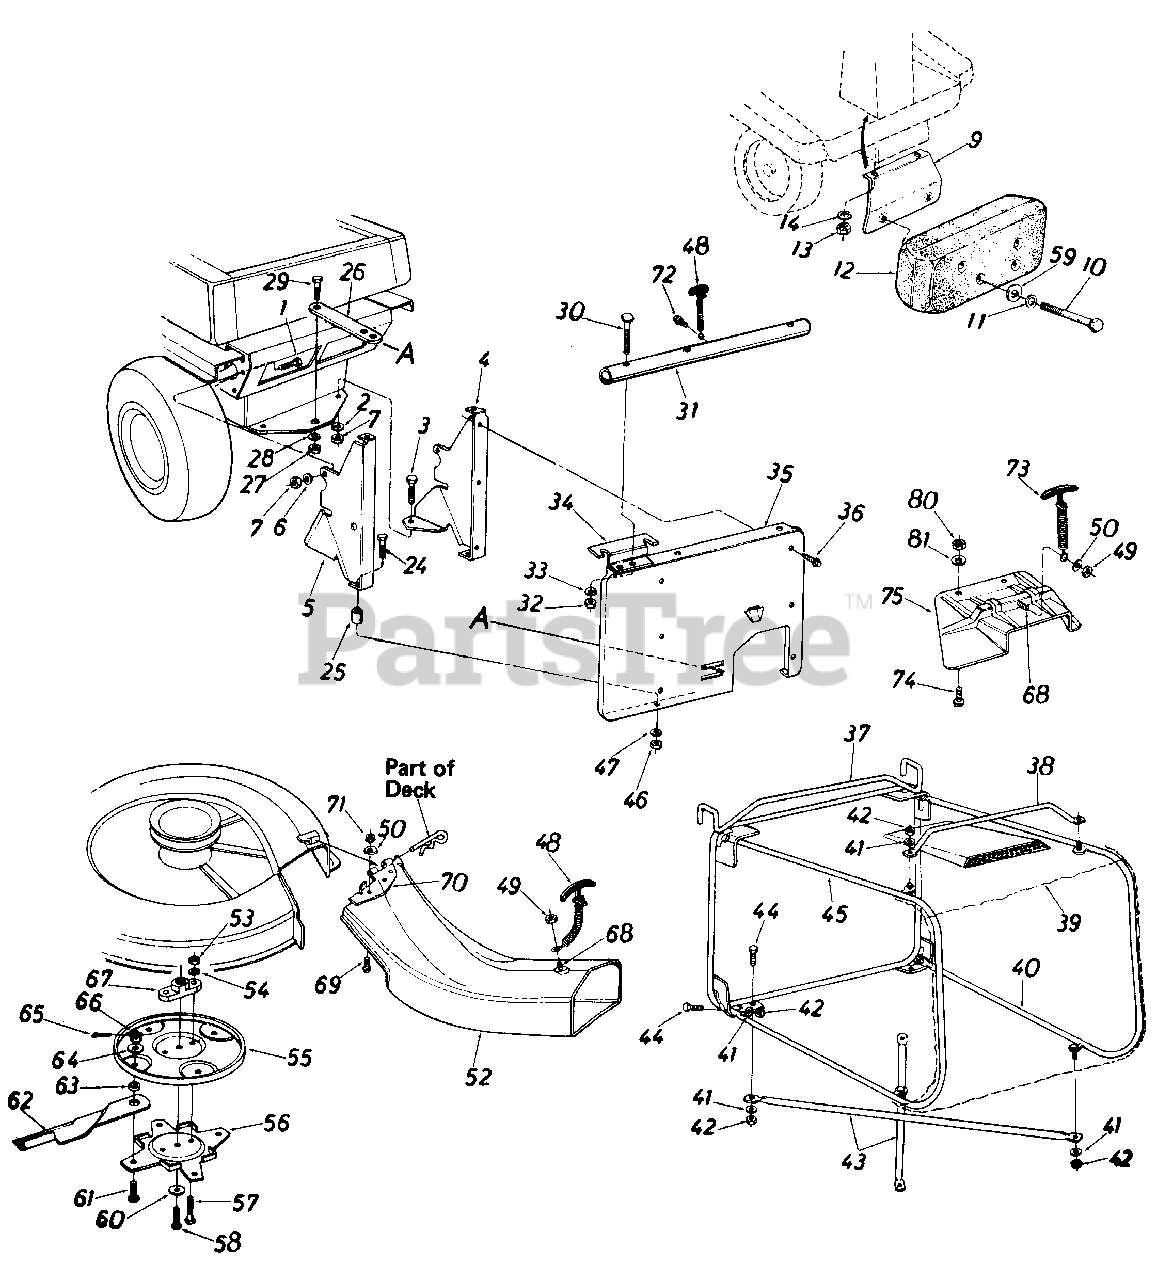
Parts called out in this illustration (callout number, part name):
1	Hex Bolt 5/16-18 x 1.0" Lg.*
2	L.-Wash. 5/16" I.D.*
3	Hex Bolt 5/16-18 x 1.0" Lg.*
4	Catcher Support Brkt - R.H.
5	Catcher Support Brkt - L.H.
6	L.-Wash. 5/16'' I.D.*
7	Hex Nut 5/16-18 Thd.
9	Counterweight Support Brkt. Ass'y .
10	Hex Bolt 3/8-16 x 4.5" Lg.*
11	Belleville Wash. .40" I.D. x .88" O.D.
12	Counterweight 38 Ibs.
13	Hex Nut 5/16-18 Thd.*
14	L.-Wash. 5/16" I.D.*
24	Hex Bolt 5/16-18 x 1.50" Lg.*
25	Spacer .380" I.D. x .47" O.D. x 1.0" Lg.
28	L.-Wash. 1/2" I.D.*
29	Hex Bolt 1/2-20 x 1.0" Lg.*
30	Curved Carriag Bolt 5/16-18 x 1.75" Lg.
33	L.-Wash. 5/16" I.D.*
34	Grass Catcher Support Plate
35	Rear Discharge Panel
36	Hex Wash. Hd. Self Tap. Scr. 1/4-20 x .50" Lg.
37	Grass Catcher Frame Ass'y.
42	Hex L.-Nut 1/2-20 Thd
43	1 Bottom Cross Brace
44	Hex Bolt 1/4-20 x .62" Lg.*
47	L-Wash. 5/16" I.D.
48	Hook Latch Ass'y.
49	Hex L.-Nut 1/4-20 Thd.
50	Fl.-Wash. 1/4" I.D.
52	R.D. Banana Chute Ass'y.
53	Hex Nut 5/16-24 Thd.*
54	L.-Wash. 5/16" I.D.*
55	Upper Blade Disc
56	Lower Blade Disc
57	Hex Bolt 5/16-24 x 1.0" Lg. (Grade 5)
58	Hex Bolt 3/8-24 x 1.0" Lg.
59	Fl.-Wash. .39" I.D. x 1.12" O.D.
60	Bell.-Wash. 39" I.D. x 1.38"
61	Shld. Bolt. .50" Dia. x .360 Spec.
62	30" Blade Tip (4-Req'd.)
63	Spacer .505" I.D. x .75" O.D. x 1.25" Lg.
64	Fl.-Wash. .50" I.D. x 1.25" O.D.
65	Cotter Pin 3/32" Dia. x 1.0" Lg.*
66	Hex Slotted Nut 1/2-20 Thd.
67	Blade Adapter
68	Hex Bolt 1/4-20 x .50" Lg.*
69	Truss Mach. Scr. 1/4-20 x .50" Lg. *
70	Chute Mounting Brkt.
71	Hex Nut 1/4-20Thd.*
72	Hex AB Tap Scr. 1/4 x .62" Lg.
73	Hook Latch Ass'y. 7" Lg.
74	Truss Mach. Scr. 1/4-20 x 50" Lg. *
75	R D Chute Extension
80	Hex L.-Nut 1/4-20 Thd.
81	Fl.-Wash. .281" I.D. x .50" O.D. x .063
